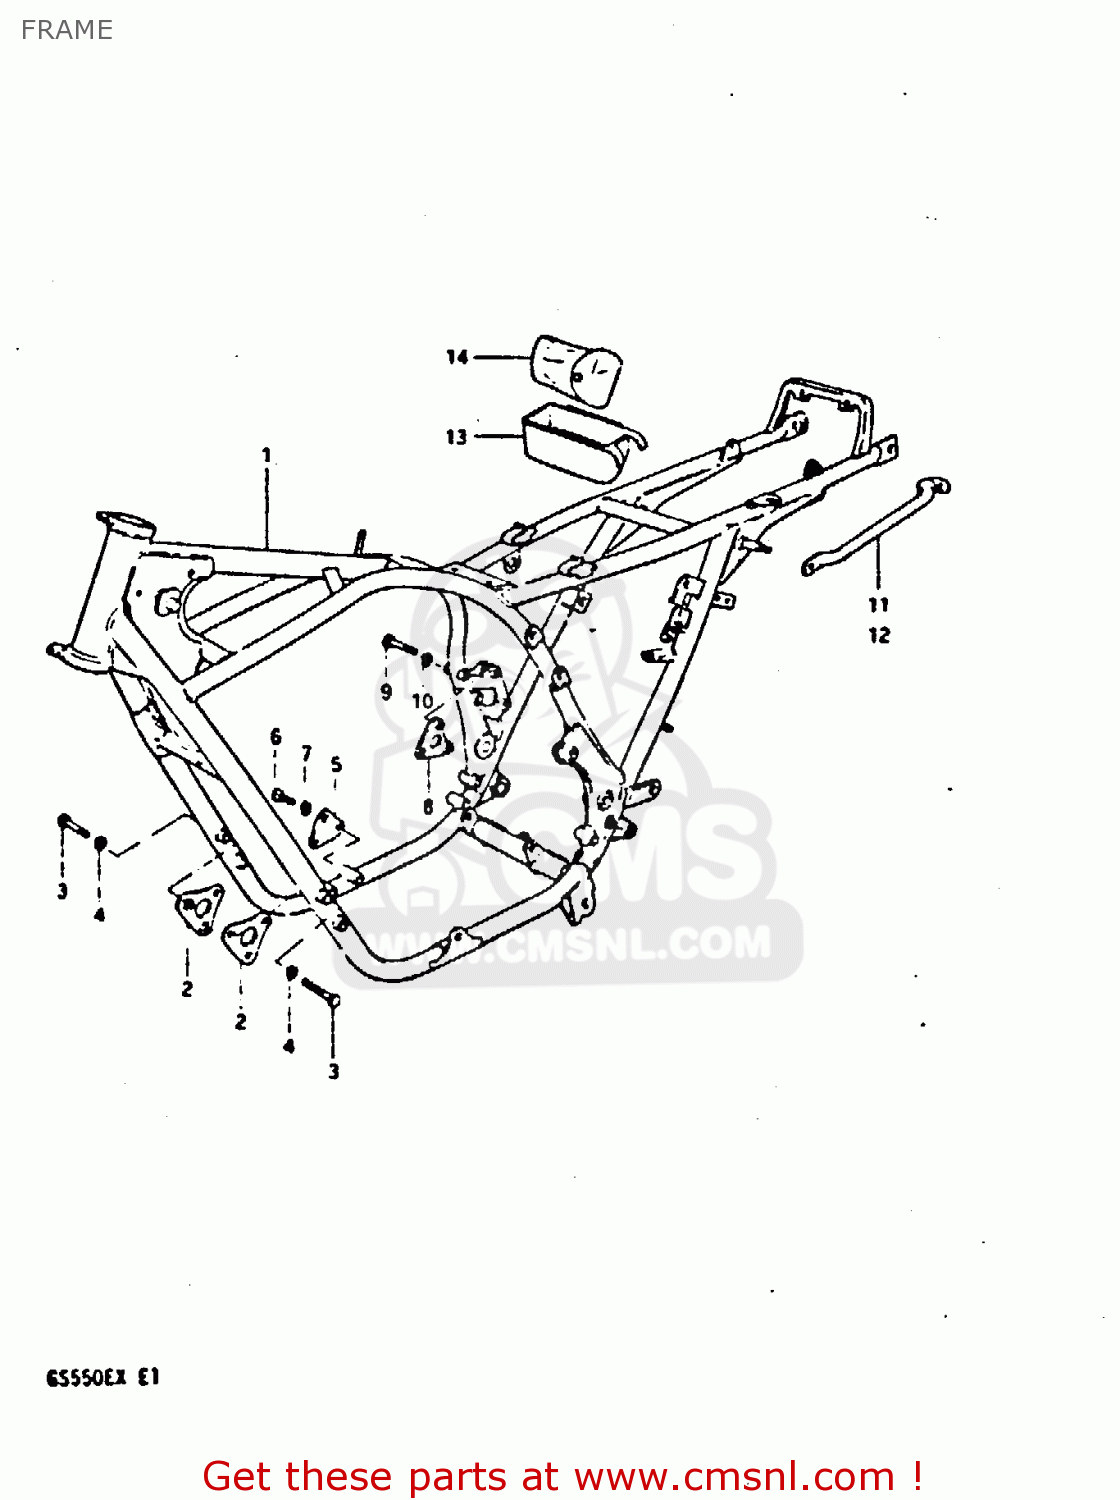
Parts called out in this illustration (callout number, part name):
1	FRAME
2	PLATE,ENGINE MOUNTING
3	BOLT
4	LOCK WASHER
5	PLATE,ENGINE MOUNTING
6	BOLT
7	LOCK WASHER
8	PLATE,ENGINE MOUNTING
9	BOLT 8X55
10	LOCK WASHER
11	GRIP,FRAME
12	GRIP, FRAME HANDLE LH
13	HOLDER,TOOL
14	TOOL SET
